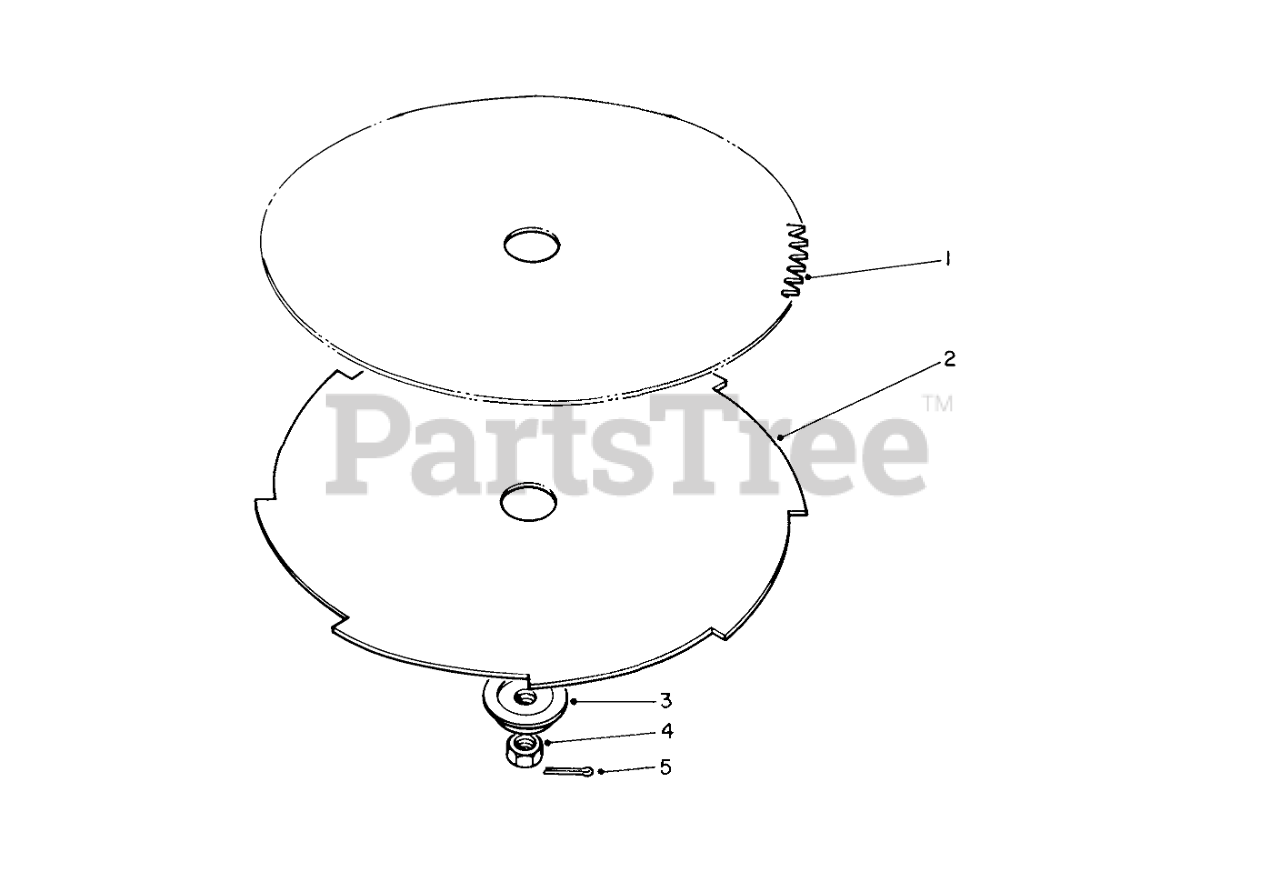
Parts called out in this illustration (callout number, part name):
1	SAW BLD PKG(8", 80T)
2	BRUSH BLD PKG(8",8T)
3	Adapter-Blade
5	1/16 X 1 LG COTTER PIN
